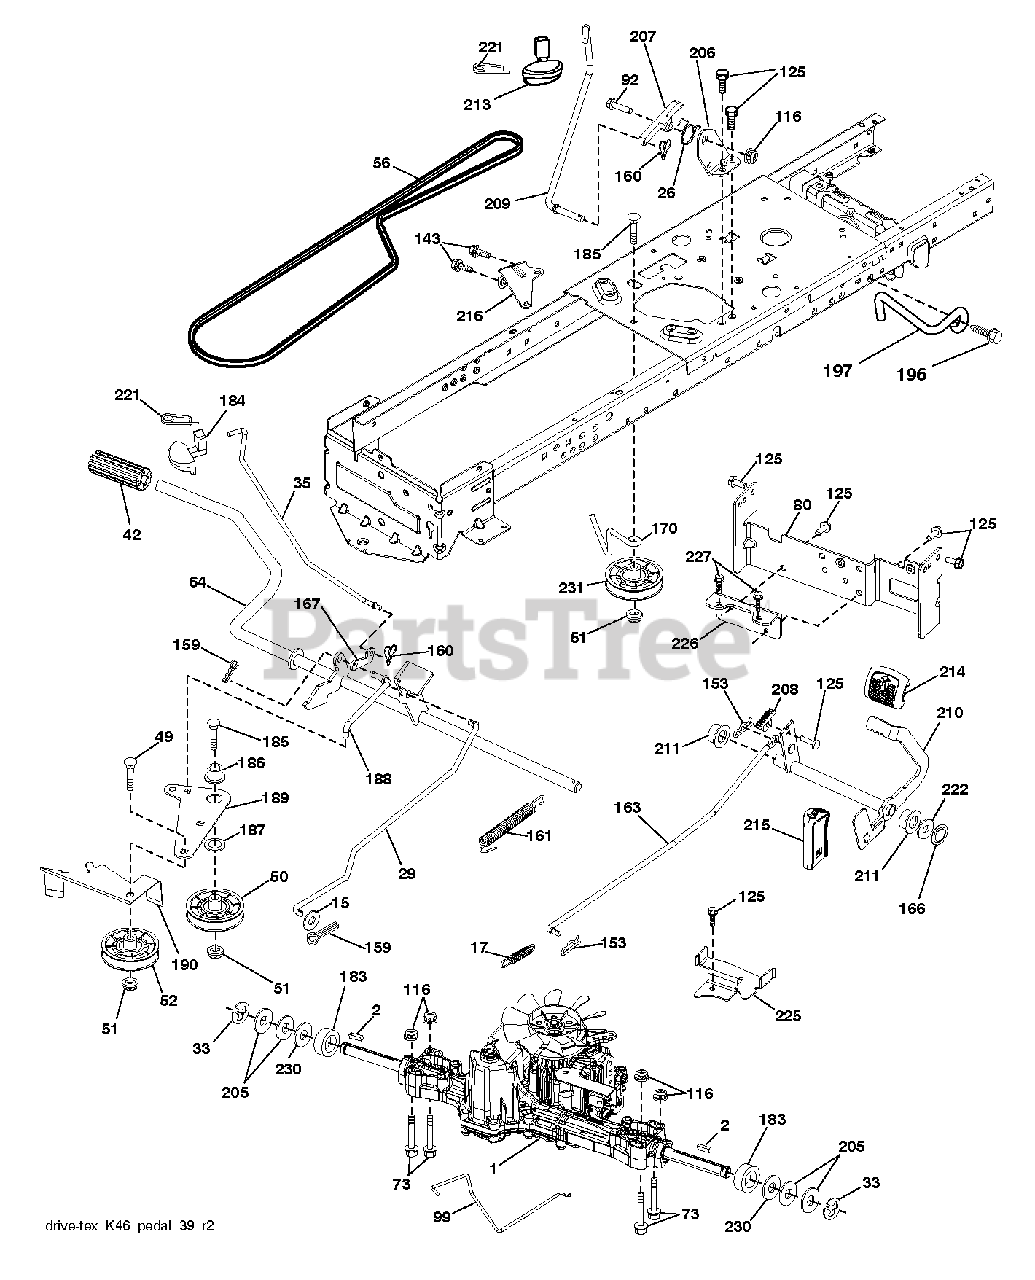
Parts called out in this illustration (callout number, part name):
2	SQUARE KEY
15	WASHER
17	SPRING, BREAK
26	SPRING.RETURN.CRUISE
29	ROD.BRAKE.K46
33	E-RING LT
35	ROD.BRKAE.PARKING.STEALTH
42	PEDAL COVER T
50	IDLER.FLAT.910.OFFSET
52	IDLER.V-GROOVE.910.OFFSET
64	SHAFT.ASM.PEDAL.BRK.CN
99	ROD.SPRING.BYPASS.K46.LT.Z
116	NUT LOCK HEX FLANGE 5/16-18
125	SCREW
143	SCREW LT
159	COTTER PIN
160	RETAINER CLIP
161	SPRING, RETURN LT
166	NUT.PUSH.625
167	LATCH BRAKE PARKING
170	KEEPER.CENTER SPAN.1.688
183	SPACER AXLE
186	SPACER.RETAINER
188	LINK.CLUTCH.GROUND DRI
189	BELLCRANK.GRDDRIVE.NST
190	KEEPER.BELLCRANK.DRIVE
196	SCREW 3/8-16X1
197	LINK.CLUTCH.ANIT-ROTAT
206	BRKT.MOUNT.LATCH.CRUIS
207	LATCH.CONTROL.CRUISE
208	GEAR.SECTOR.CONTROL.CR
209	ROD.CONTROL.CRUISE.STE
210	ROCKER.ASM.PEDAL.CONTR
211	BEARING RER
213	KNOB.CONTROL.CRUISE
214	PAD PEDAL FORWARD
215	PEDAL.REVERSE.TEX.GT.4
216	BRKT.PULLEY.IDLER.WTEX
221	RETAINER.SPRING.CLIP.H
222	WASHER 21/32 X 1-1/4 X 10 GA.
225	KEEPER.BELT.TRANSAXLE.
226	BRACKET MOUNT TORQUE
231	PULLEY VGROOVE
